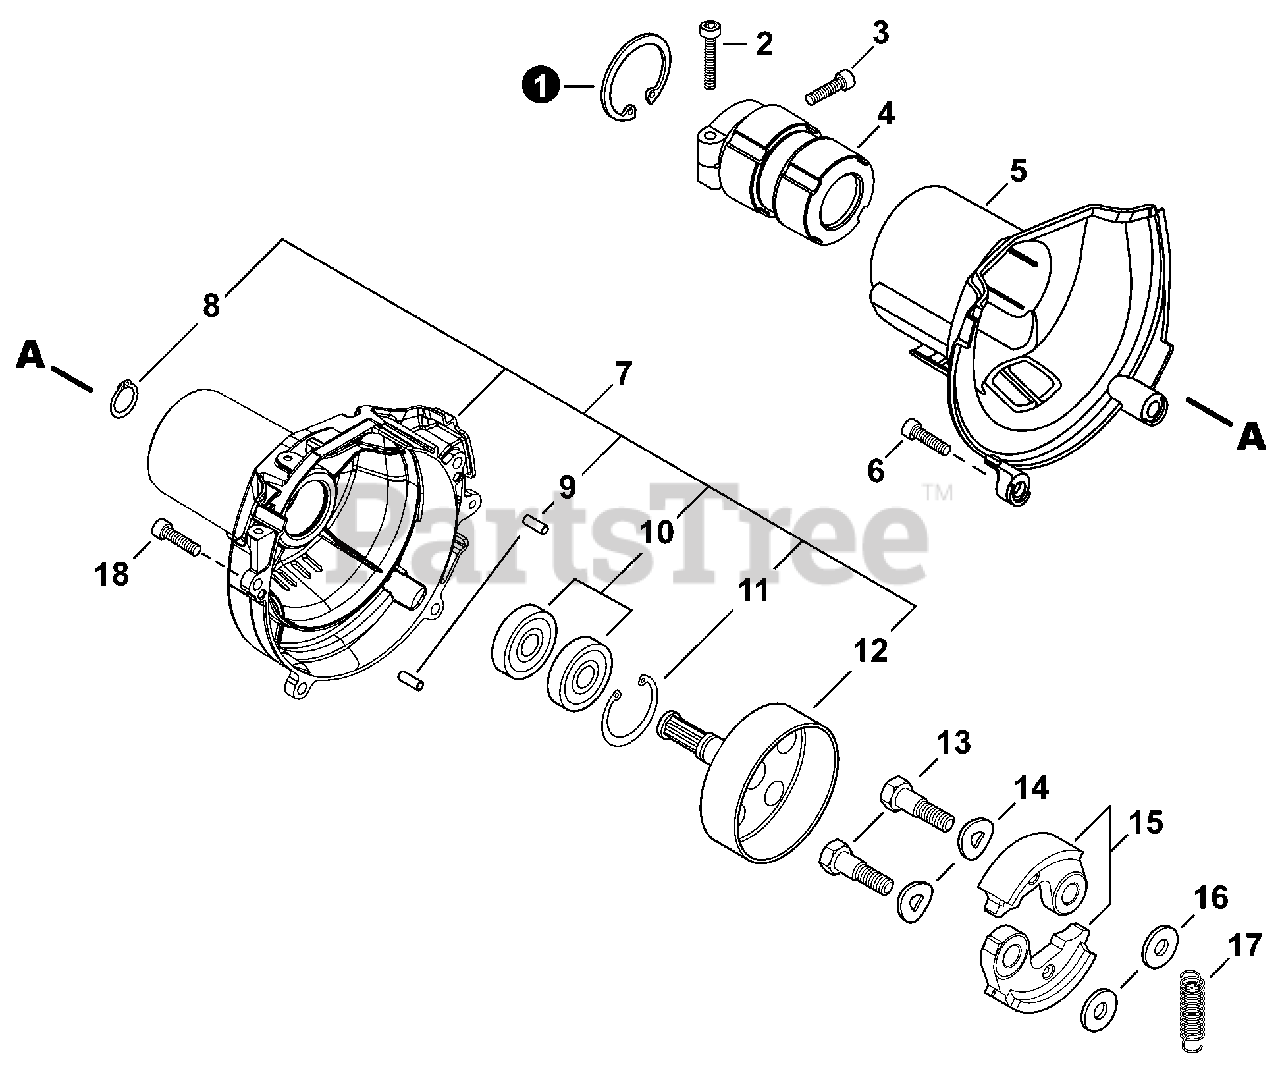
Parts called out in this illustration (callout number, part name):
1	RING, RETAINING Ø45
2	BOLT, TORX 5×25
3	BOLT, TORX 5×12
4	HOLDER, MAIN PIPE
5	PROTECTOR, FAN COVER
6	BOLT, TORX 5×20
7	COVER ASSY, FAN
8	RING, RETAINING - 12
9	PIN, LOCATING 4×8
10	BEARING, BALL 6001
11	RING, SNAP 28
12	DRUM, CLUTCH
13	BOLT, CLUTCH 8×7.9×M6
14	WASHER, SPRING 8.5×16×0.5
15	SHOE, CLUTCH
16	WASHER 6.2×19×1.0
17	SPRING, CLUTCH
18	BOLT, TORX 5×20
